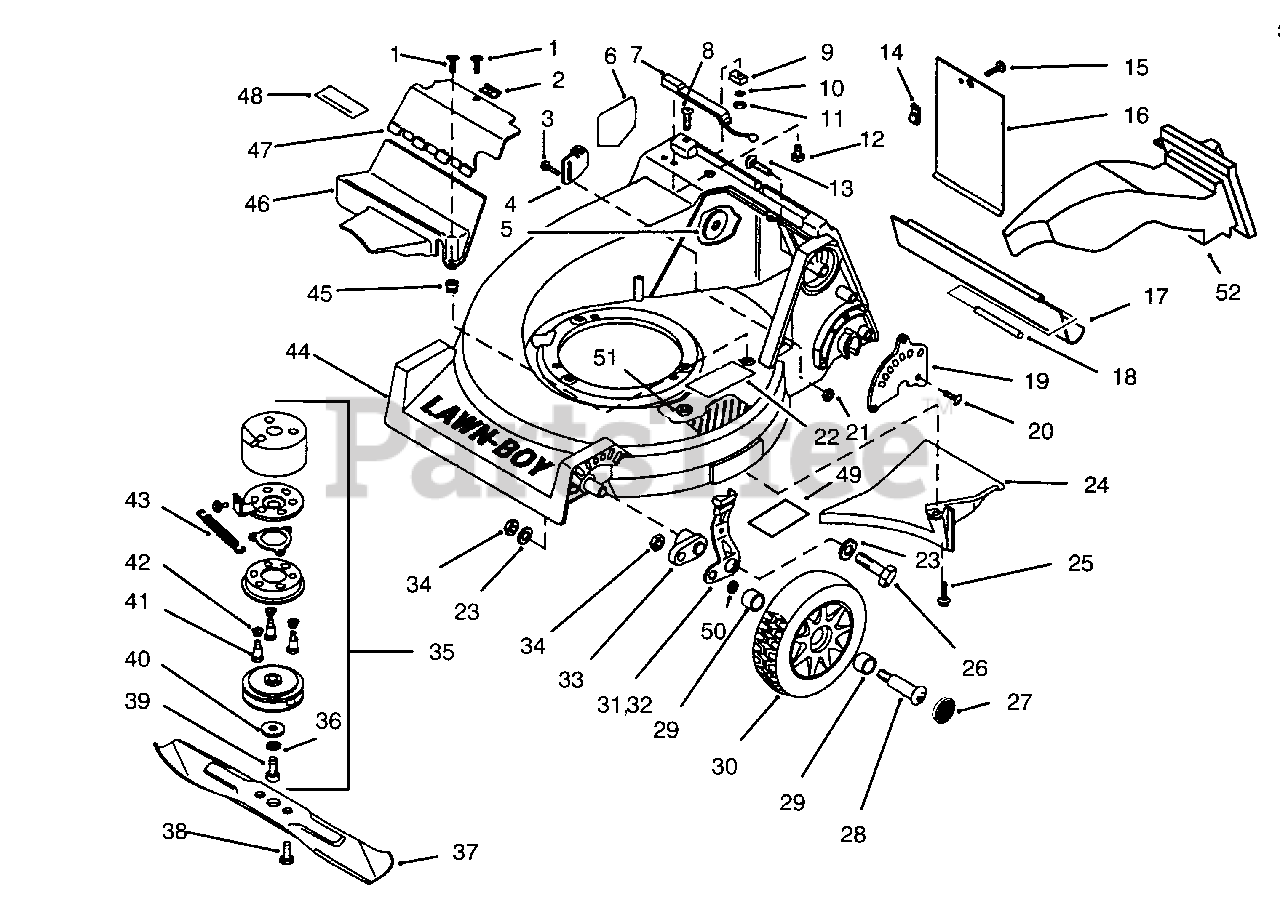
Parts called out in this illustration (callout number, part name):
2	Speednut
3	Screw-Anchor to Housing
4	Cable-Anchor
5	Washer-R.H. Handle Mtg.
6	Decal-Blade Warning
7	Assy.-Switch, Bag Lock
9	Assembly-Magnet
10	Lockwasher
13	Bolt-Handle Mounting
14	Speednut
16	Door-Access
17	Shield-Trailing
19	Plate-Height Adjustment
21	Nut-Lock
22	Decal-Foot Pad
28	Bolt-Wheel
29	Bushing-Wheel
30	Assembly Wheel & Tire (Incl. Ref. No. 29)
31	Assy.-Knob & Spring, L.H.
33	Arm-Front Height Adj.
34	Nut-Jam
35	Clutch & Brake Assy (Incl. Ref. No. 36, & 39-43)
36	Lockwasher
37	Blade-21"
38	Screw-Blade
42	Spring-Compression
43	Spring-Extension
44	Assembly-Housing (Incl. Ref. No. 5-6,13, & 24-25)
45	Grommet
46	Cover-Lower Drive
